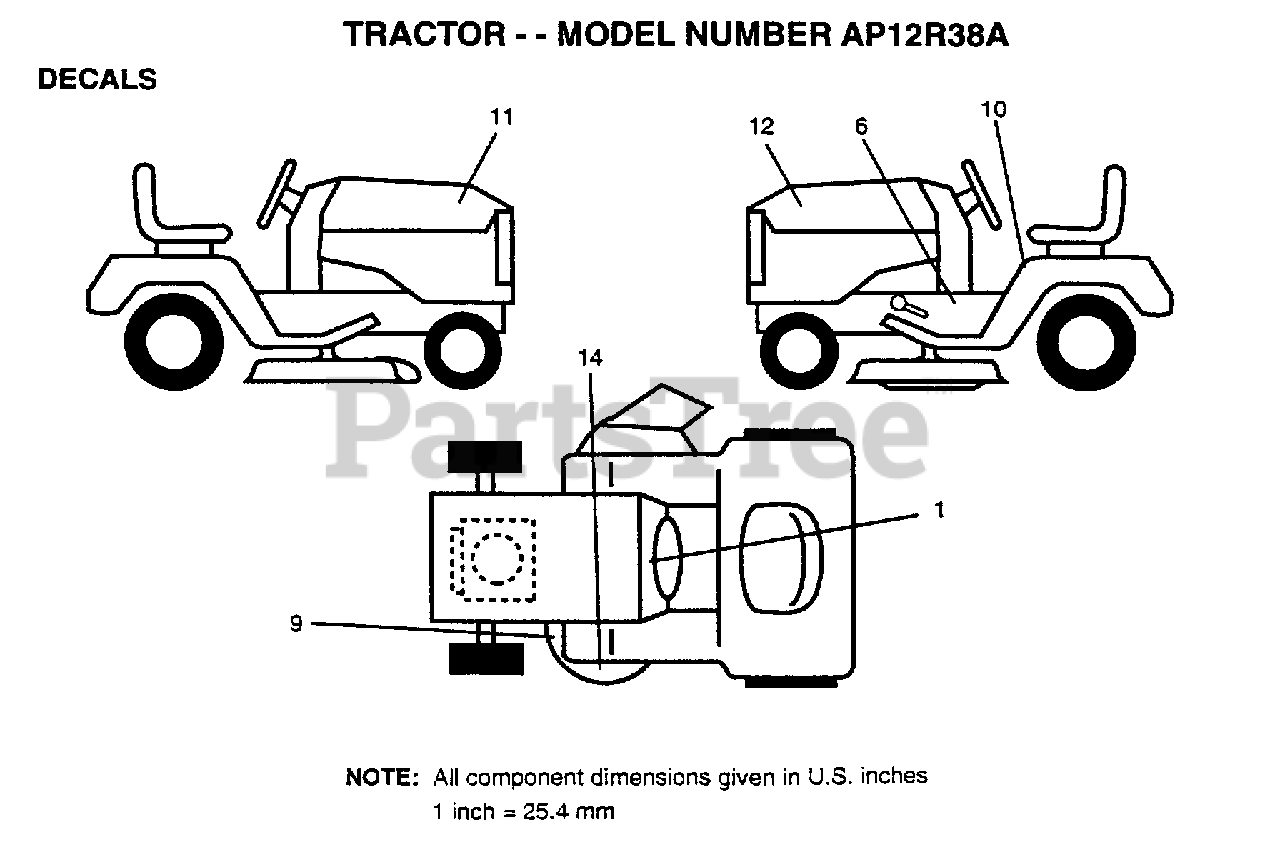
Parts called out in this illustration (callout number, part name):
1	DECAL.INST.OPER
6	IND HGT DECK DECA
9	DECAL
10	DECAL
11	DECAL.HD.RH.12HP
12	DECAL.HD.RH.12HP
14	"DECAL,ENVIRO DECK"
